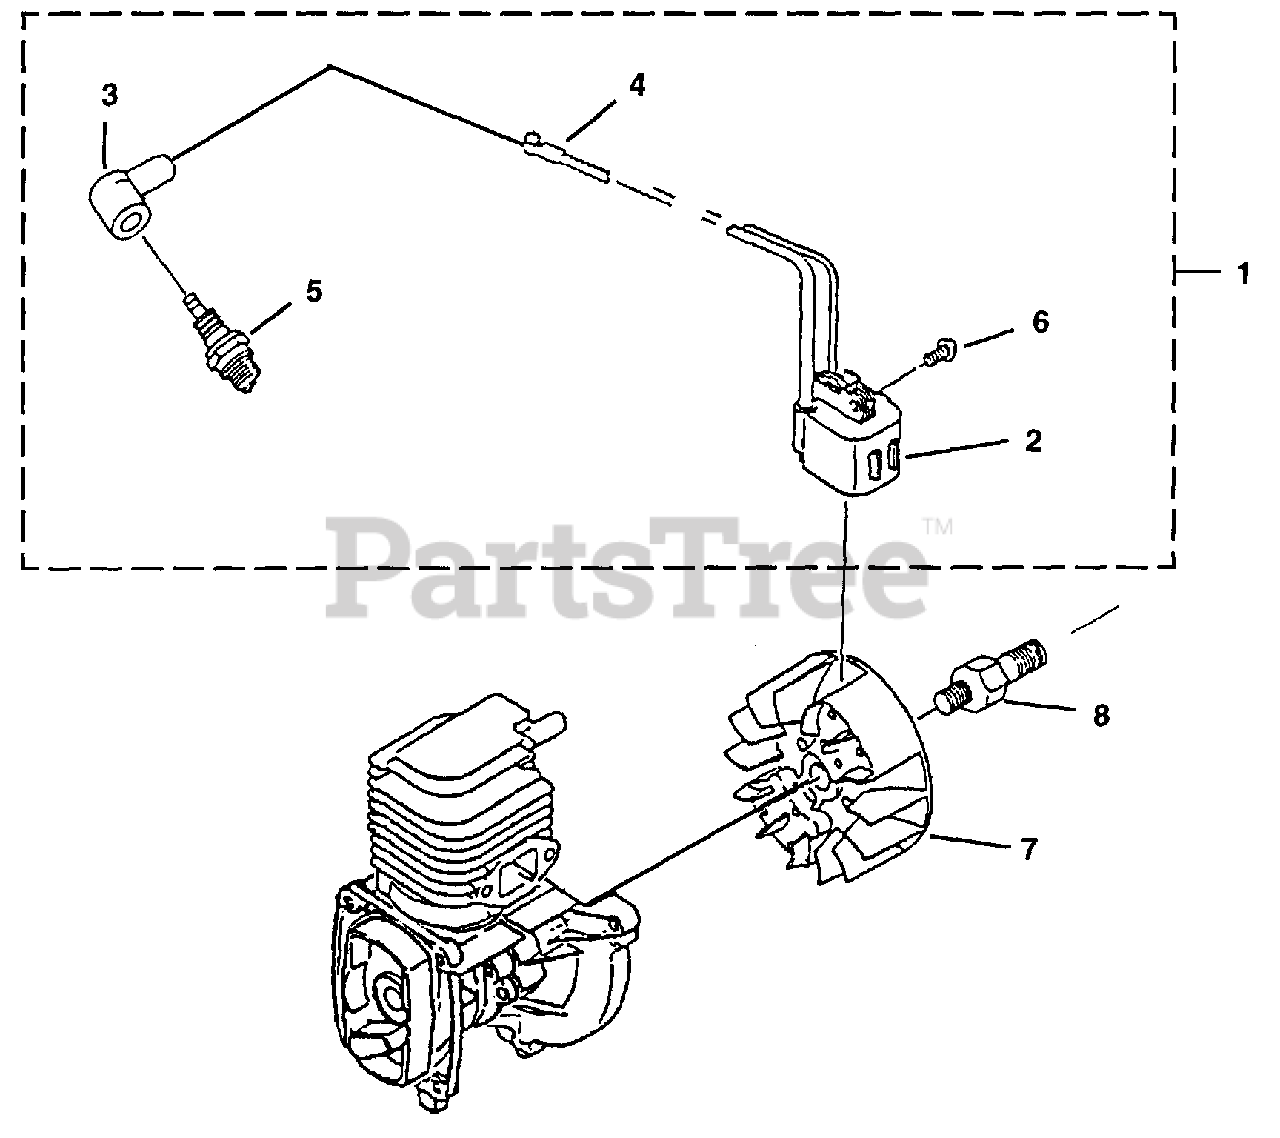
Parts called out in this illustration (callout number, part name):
1	IGNITION KIT
2	MODULE-Ignition
3	CAP-Plug
4	SPRING-Plug Cap
5	SPARK PLUG
6	SCREW ASSEMBLY (M4 x 20)
8	SHAFT-Fan
